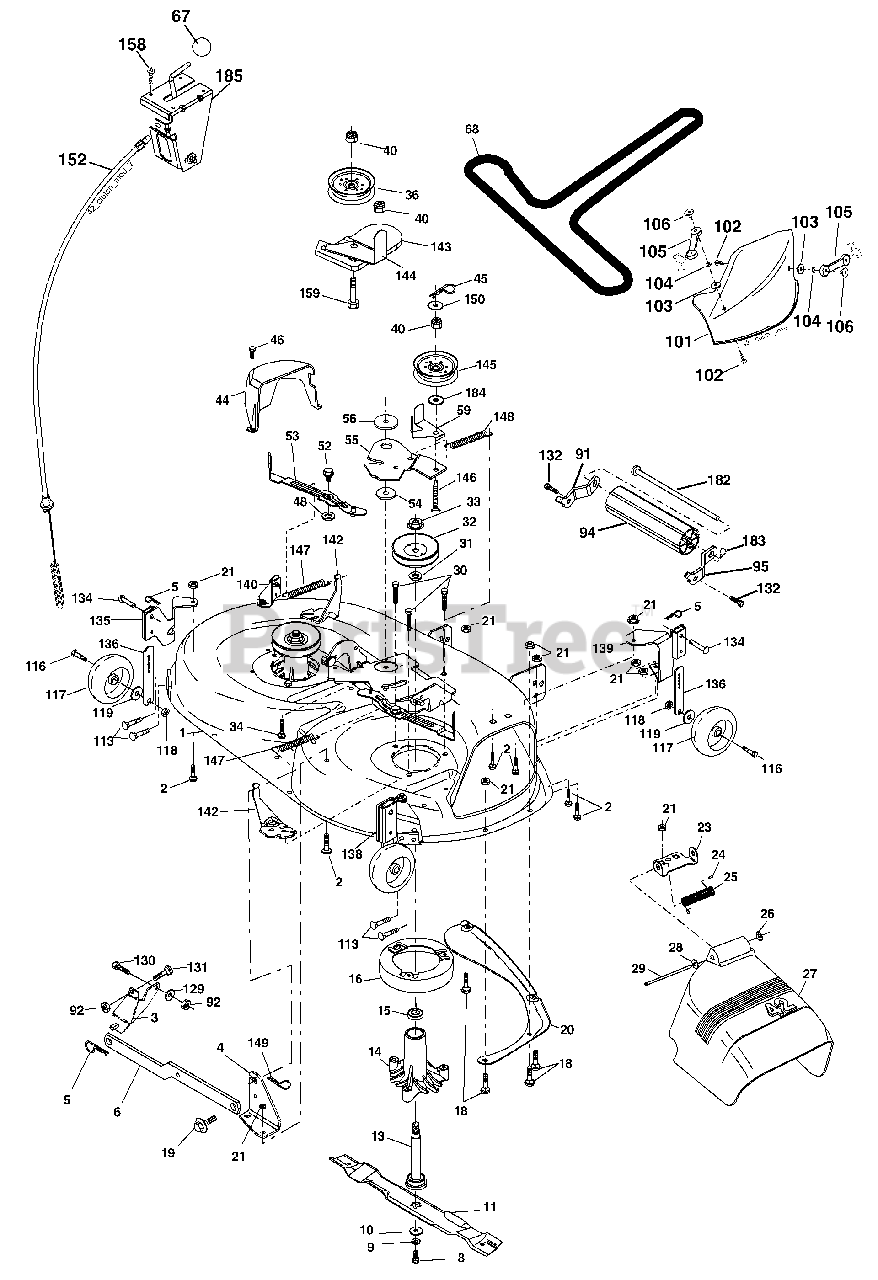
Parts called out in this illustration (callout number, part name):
1	Mower Deck Assembly, 42"
2	Bolt
3	Bracket Asm Fr. Sway Bar 3/42
4	Bracket Asm Deck 42" Sway Bar
5	Retainer Spring
6	Bar Sway Deck
8	Bolt 3/8-24 x 1.25 Gr. 8 patched
9	Washer, Lock
10	Washer, Hardened
11	Blade, Mulching 42" Std
11	Blade Mulching 42" Premium
11	Blade Mower 42" Hi-Lift
13	Shaft Assembly, Mandrel, Vented
14	Housing, Mandrel, Vented
15	Bearing, Ball, Mandrel
16	Stripper, Mandrel Deck
18	Bolt, Carriage 5/16-18 x 5/8
19	Bolt, Shoulder
20	Baffle, Vortex
21	Nut
23	Bracket, Deflector Mower 42"
24	Cap, Sleeve 80 x 112 Blk Mower
25	Spring, Torsion, Deflector 2 52
26	Nut, Push Phos & Oil
27	Shield, Deflector 42" Blk
28	Washer 11/32 x 5/8 x 16 Ga.
29	Rod, Hinge 42" 6 75 W/G
30	Screw Thdrol
31	Washer, Spacer Mower Vented
32	Pulley, Mandrel
33	Nut, Toplock
34	Bolt Carr SH 3/8-16 x 1-1/2 Gr.5
36	Pulley, Idler, Flat
40	Nut Lock 3/8-16
44	Guard, Mandrel, LH
45	Retainer
46	Screw, Thdrol 1/4-20 x 5/8 T
48	Washer, Hardened
52	Bolt, Shoulder 5/16-18 unc
53	Arm Assembly, Pad, Brake
54	Washer, Hardened
55	Arm, Idler
56	Spacer, Retainer
59	Guard TUV Idler
67	Knob
68	V-Belt, 42" Mower
91	Bracket Asm Noseroller LH
92	Nut Lock Hex w/Ins 3/8-16 unc
94	Roller Nose 38 & 42
95	Bracket Asm Noseroller RH
101	Mulcher Cover
102	Screw, Pan Hd Phillip 10-24 x 5/8
103	Washer, Flat
104	Washer, Lock
105	Latch Assembly
106	Nut, Weld
113	Screw 5/16-18 x 3/4
116	Bolt, Shoulder
117	Wheel, Gauge
118	Nut Centerlock 3/8-16
119	Washer 3/8 x 7/8 x 14 Ga.
129	Washer 13/32 x 13/16 x 12 Ga.
130	Bolt Fin HEx 3/8-16 unc x 1 Gr. 5
131	Bolt RDHD SQNK 3/8-16 unc x 1
132	Screw 3/8-16 x .75
134	Pin Head Rivet
135	Bracket Asm. Whl Ga. R LH
136	Bar Adjusting Gauge Wheel
138	Bracket Asm Whl Ga. R RH
139	Bracket Asm. Whl Ga. F RH
140	Bracket Asm Whl Ga. F LH
142	Arm Spring Brake Mower
143	Bracket Arm Idler 42"
144	Keeper Belt 42" Clutch Cable
145	Pulley Idler Flat
146	Bolt Carriage Idler
147	Spring Extension
148	Spring Return Idler
149	Retainer Spring Yellow
150	Washer 9/32 x 3/4 x 10 Ga.
152	Clutch Cable 42"
158	Screw Hex Thd Cut 1/4-20 x 1/2
159	Bolt Rdhd Sqn 3/8-16 unc x 1-3/4
182	Rod Roller Nose
183	Retainer Spring
184	Washer 13/32 x 7/8 x 10 Ga.
185	Head Asm Cable Clutch
